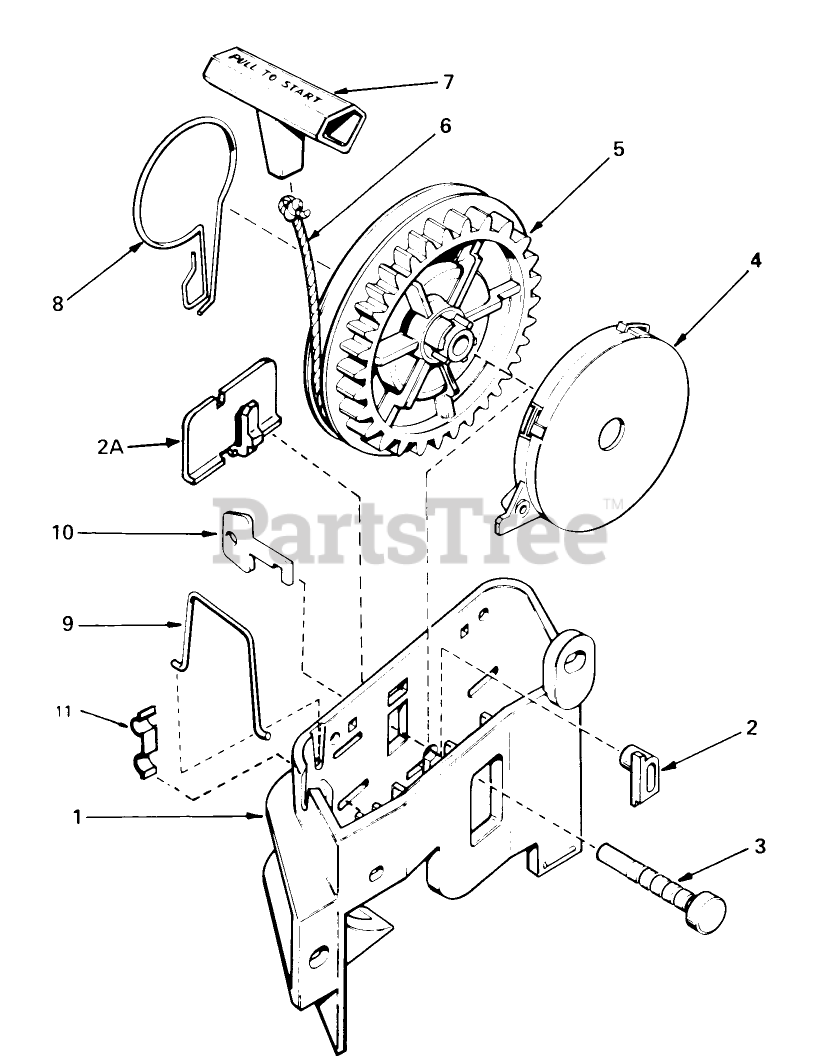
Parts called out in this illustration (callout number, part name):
1	Bracket Starter
2	Pawl, Locking Not used on all engine models)
2A	Clip, Starter Bracket (Used On Starters Not Equipped With Pawl, Ref. No. 2)
3	Pin-Pulley
4	Spring Assy., Rewind (Incl. Ref. #3)
5	Pulley
6	Rope-Starter (98 cut to length)
7	Handle-Starter
8	Brake
9	Clip-Rope
10	Key (Not Used On All Engine Models
11	Clip-Bowden Wire (Not used on all engine models)
